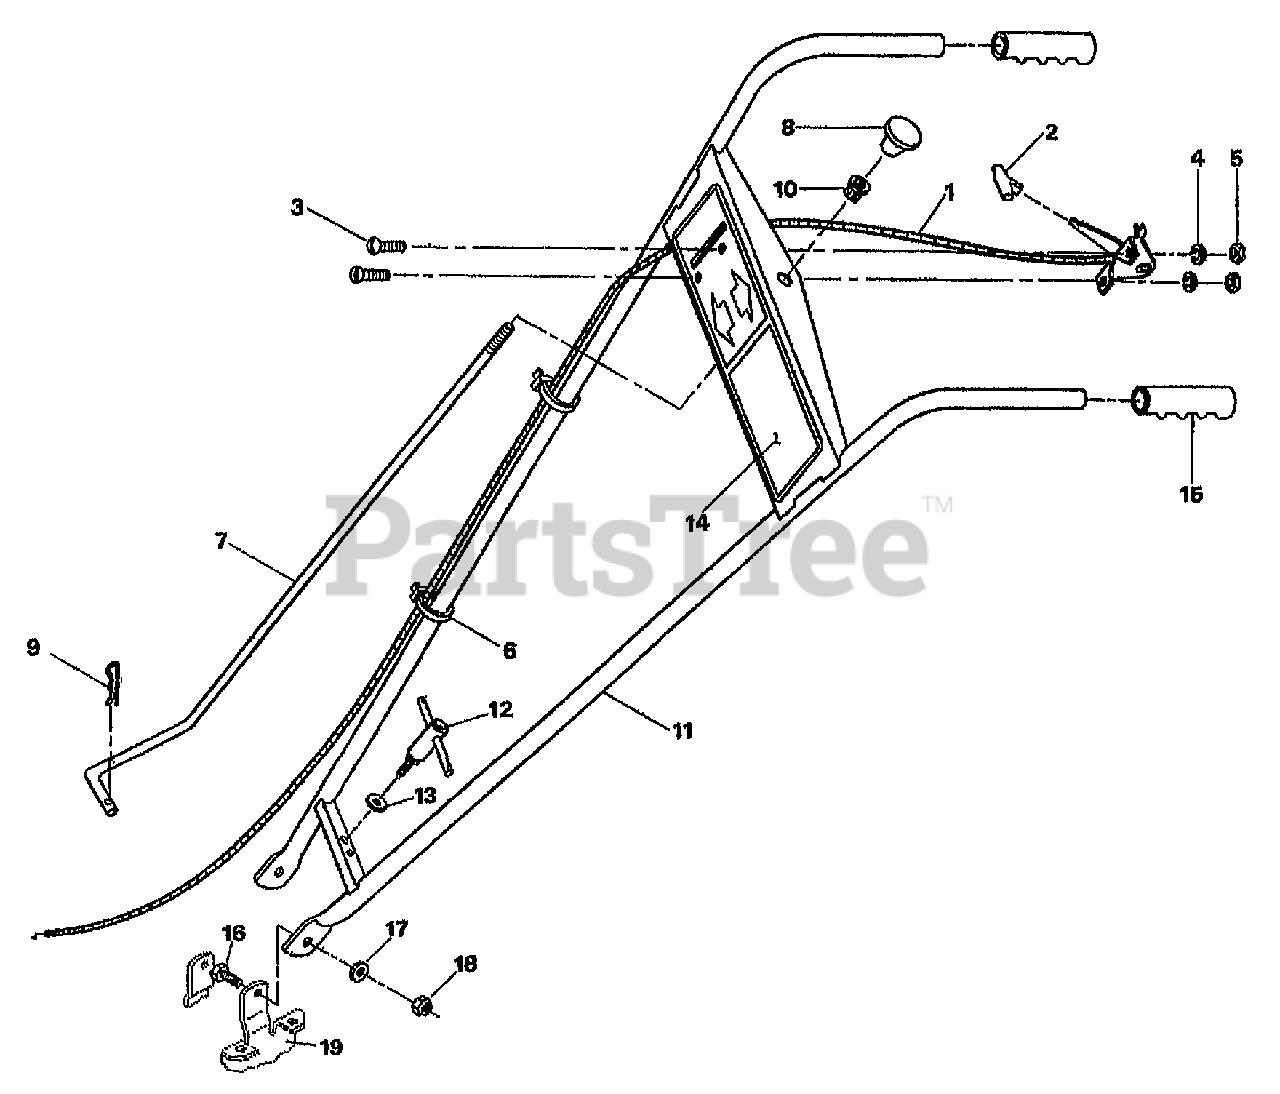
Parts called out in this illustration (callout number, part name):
1	CABLE-THROTTLE & KNOB (Inc. 2)
2	KNOB-THROTTLE CABLE
3	SCR-RH M10-32X.5 MACH
4	WASHER-LK M10
5	NUT-HH M10-32X.125
6	TIE-RED
7	ASSM-DR CONTROL ROD
8	KNOB-DRIVE CNTRL ROD
9	PIN-CLIP .08
10	GROMMET-PLASTIC
11	ASSM-HANDLEBAR (Inc. 12-14 & 2 #15)
12	ASSM-CLAMP
13	WASHER-FLAT 3/8 SAE
13	WASHER-TAB 3/8" (Used on S/N M0008204- M0030389 Only)
14	DECAL-CONTROL PANEL (Operating Instructions)
15	GRIPS-HANDLEBAR
16	SCR-HH 3/8-16X1.0 G5 ZP
17	WASHER-FLAT 3/8 SAE
18	NUT-LOCK 3/8-16 NYLON ZP
19	ENGINE with HANDLEBAR MOUNTING BRACKET
